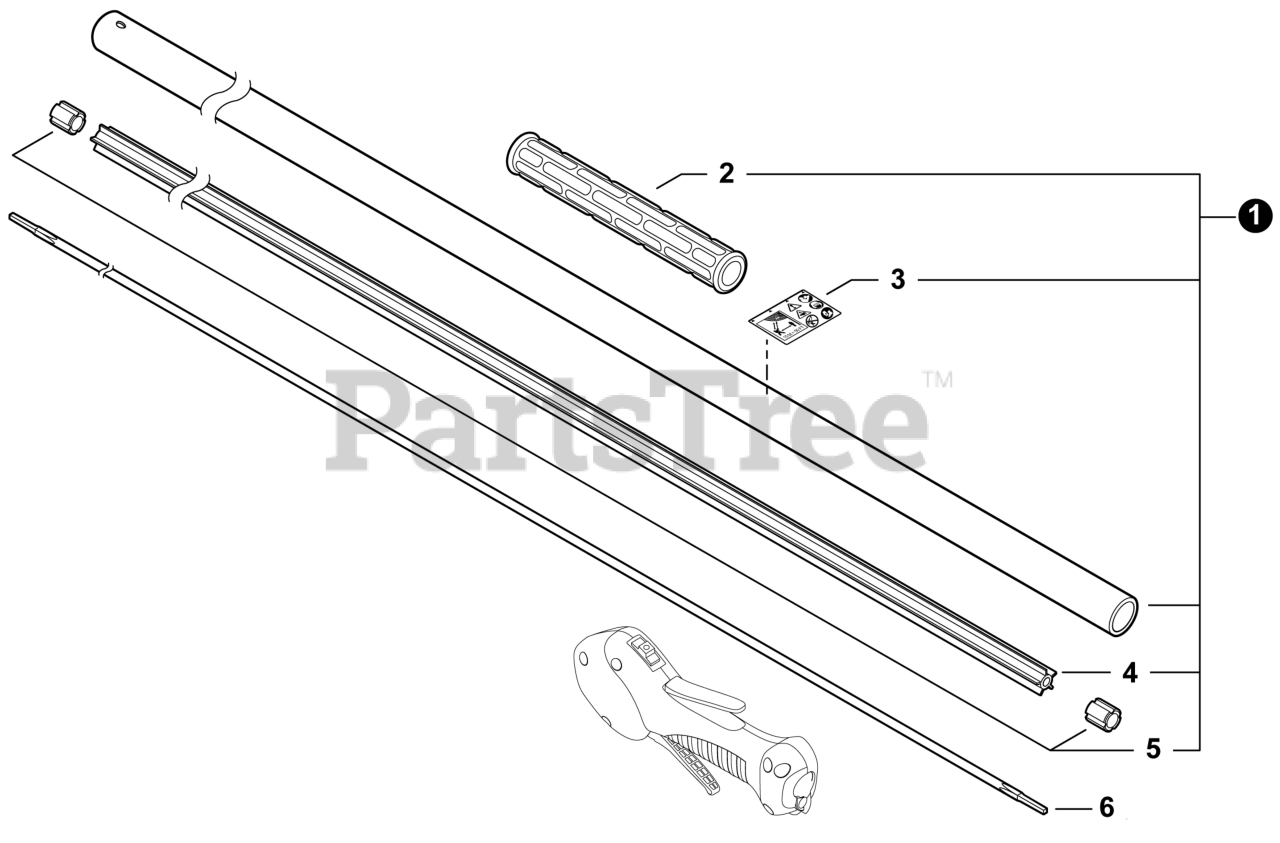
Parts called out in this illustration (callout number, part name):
1	MAIN PIPE ASSY
2	GRIP, FRONT
3	LABEL - CAUTION ISO
4	LINER - FLEXIBLE
5	STOPPER
6	DRIVESHAFT - FLEXIBLE
